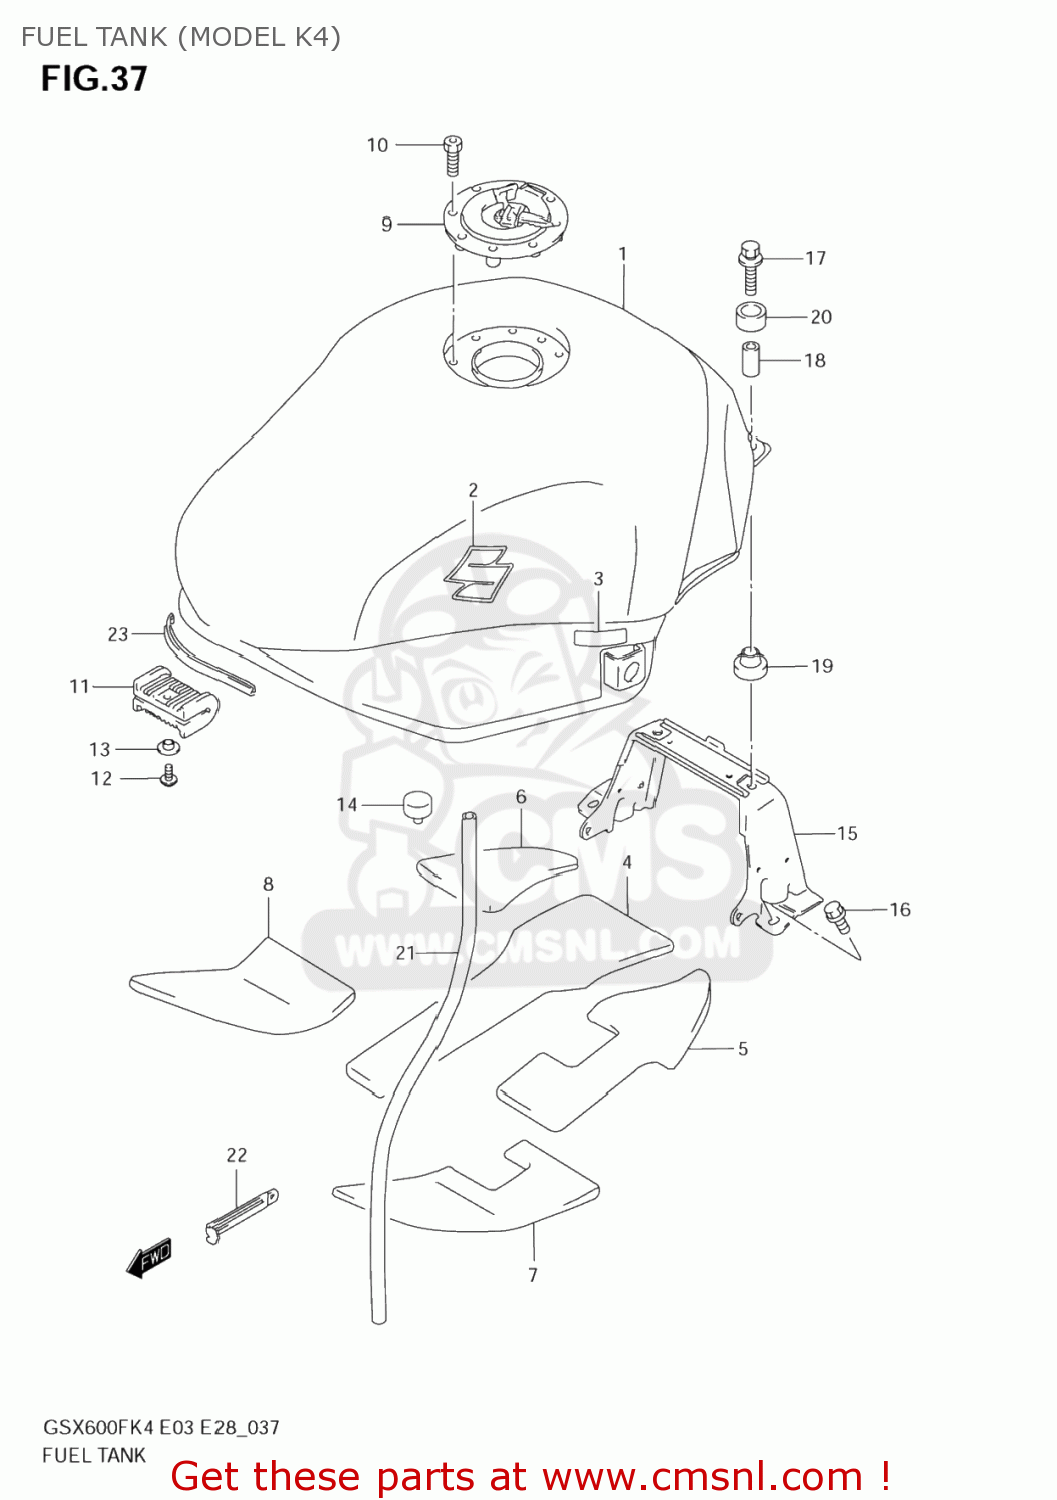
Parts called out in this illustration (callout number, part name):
1	TANK ASSY, FUEL (BLUE)
2	J¥EMBLEM
3	PROTECTOR(12X40)
4	SHIELD,FUEL TANK HEAT NO.1
5	SHIELD,FUEL TANK HEAT NO.2
6	SHIELD,FUEL TANK HEAT NO.3
7	SHIELD,FUEL TANK HEAT NO.4
8	SHIELD,FUEL TANK HEAT NO.5
9	CAP SET,FUEL TANK
10	BOLT(5X20)
11	CUSHION,FUEL TANK FR
12	SCREW 5X12
13	WASHER
14	CUSHION
15	BRACKET,FUEL TANK RR
16	BOLT
17	BOLT(6X30)
18	SPACER(6.5X9X18)
19	CUSHION
20	CUSHION
21	HOSE,FUEL TANK WATER DRAIN
22	CLAMP(L:120 T:1.0)
23	MOLDING,FUEL TANK
